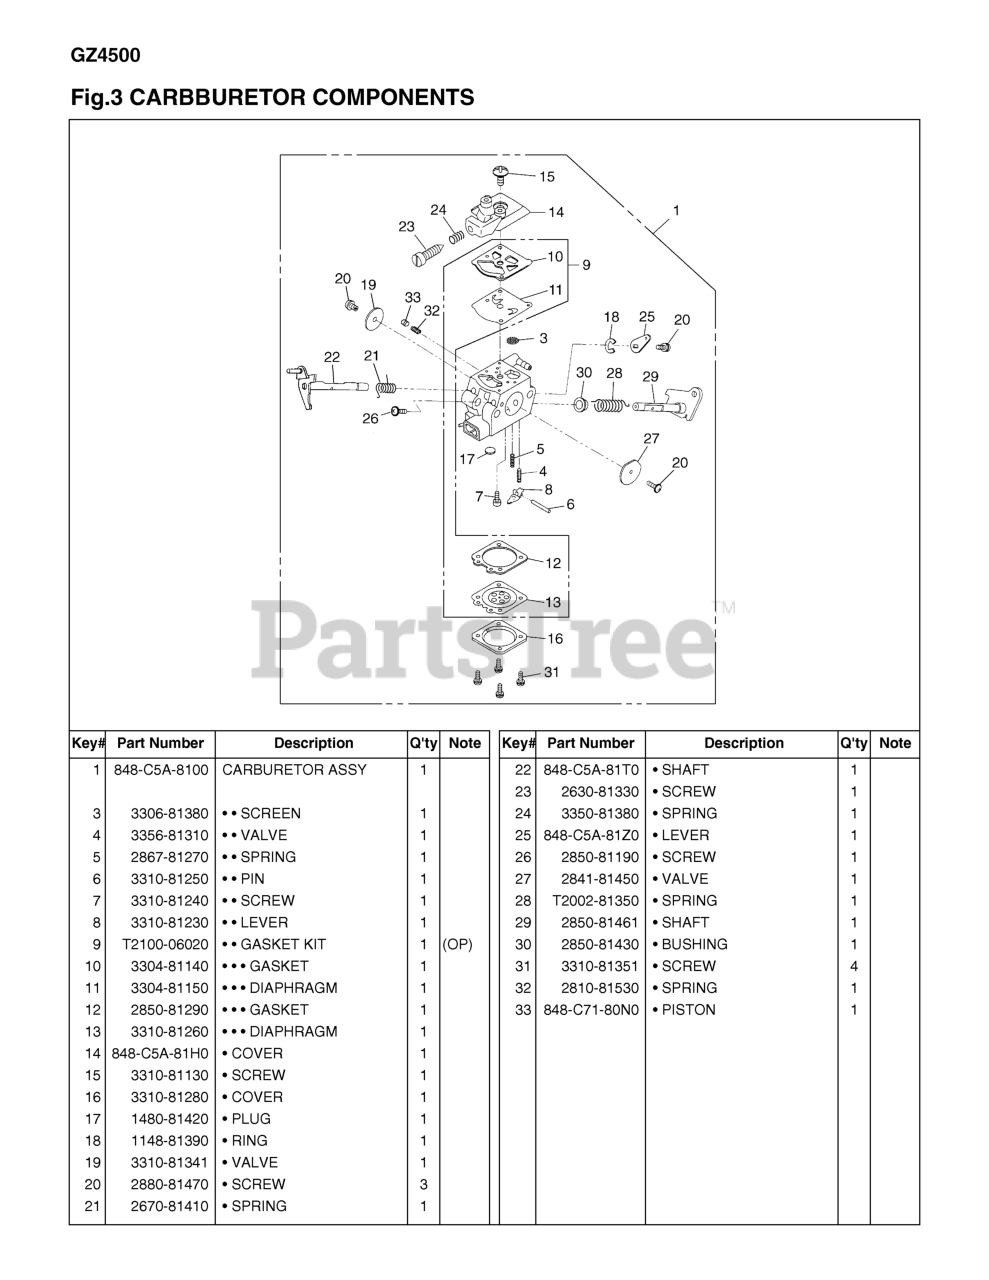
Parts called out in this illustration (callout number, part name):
1	CARBURETOR ASSY
4	VALVE, INLET
5	SPRING (RPLS 2841-81270)
6	PIN, METERING LEVER
8	LEVER
9	KIT, GASKET (G3800AVS)
10	GASKET, PUMP
11	KIT ONLY
13	DIAPHRAGM (USE 4810-81260)
14	COVER
17	PLUG, WELSH
20	SCREW (RPLS 3310-81360)
21	SPRING, RETURN
22	SHAFT
24	SPRING, IDLE
25	LEVER
29	SHAFT, CHOKE
31	SCREW ASSEMBLY
33	PISTON
